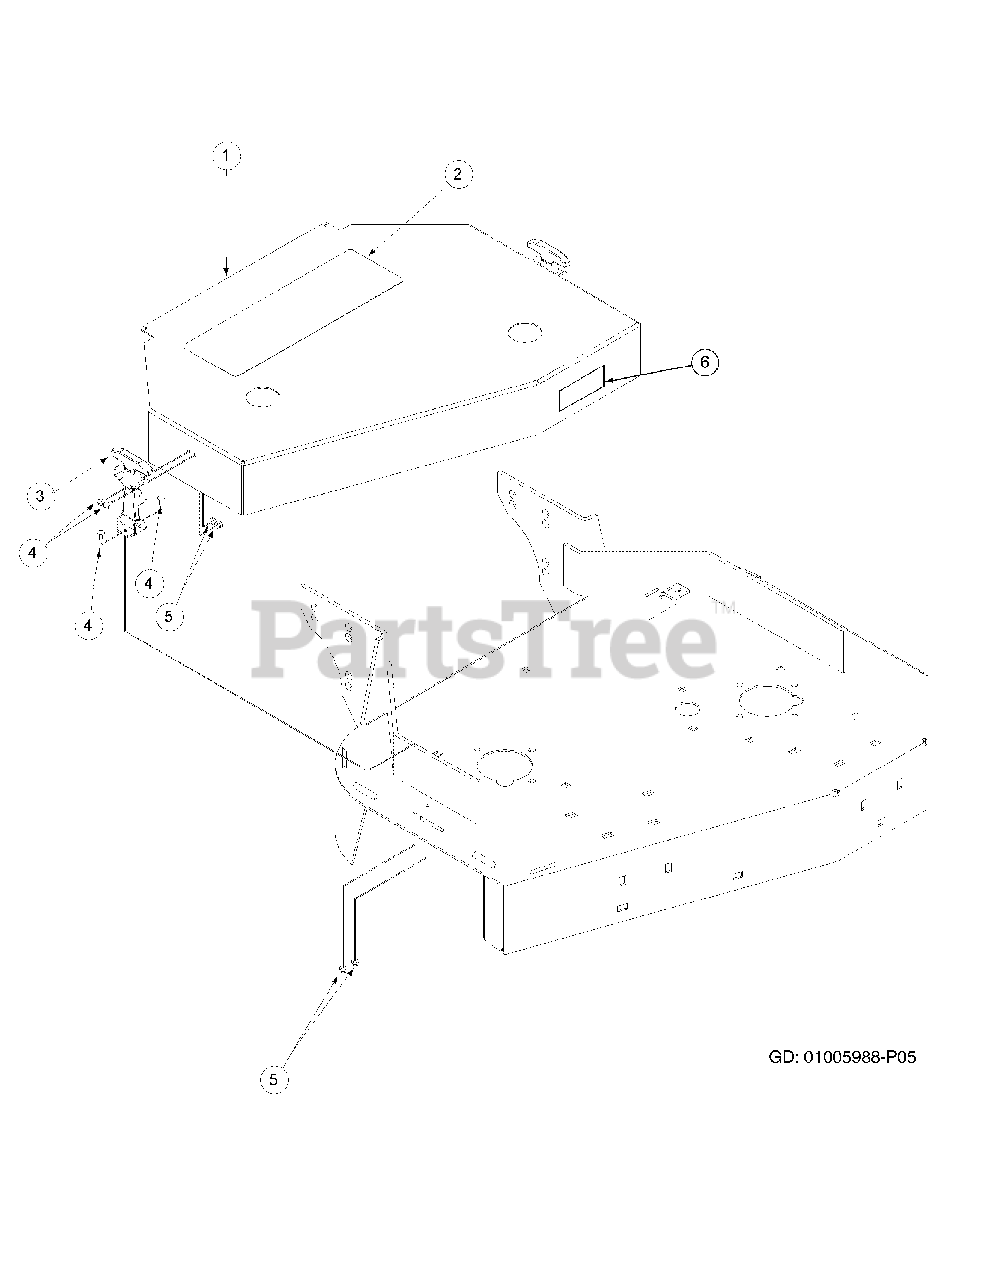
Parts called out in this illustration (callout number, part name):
1	Deck Cover, 32"
2	Label Commercial Mower
3	Rubber Hood Latch
4	Machine Screw, 10-24 x 1/2
5	Lock Nut, Nylon Insert, 10-24
6	Label, G1332
